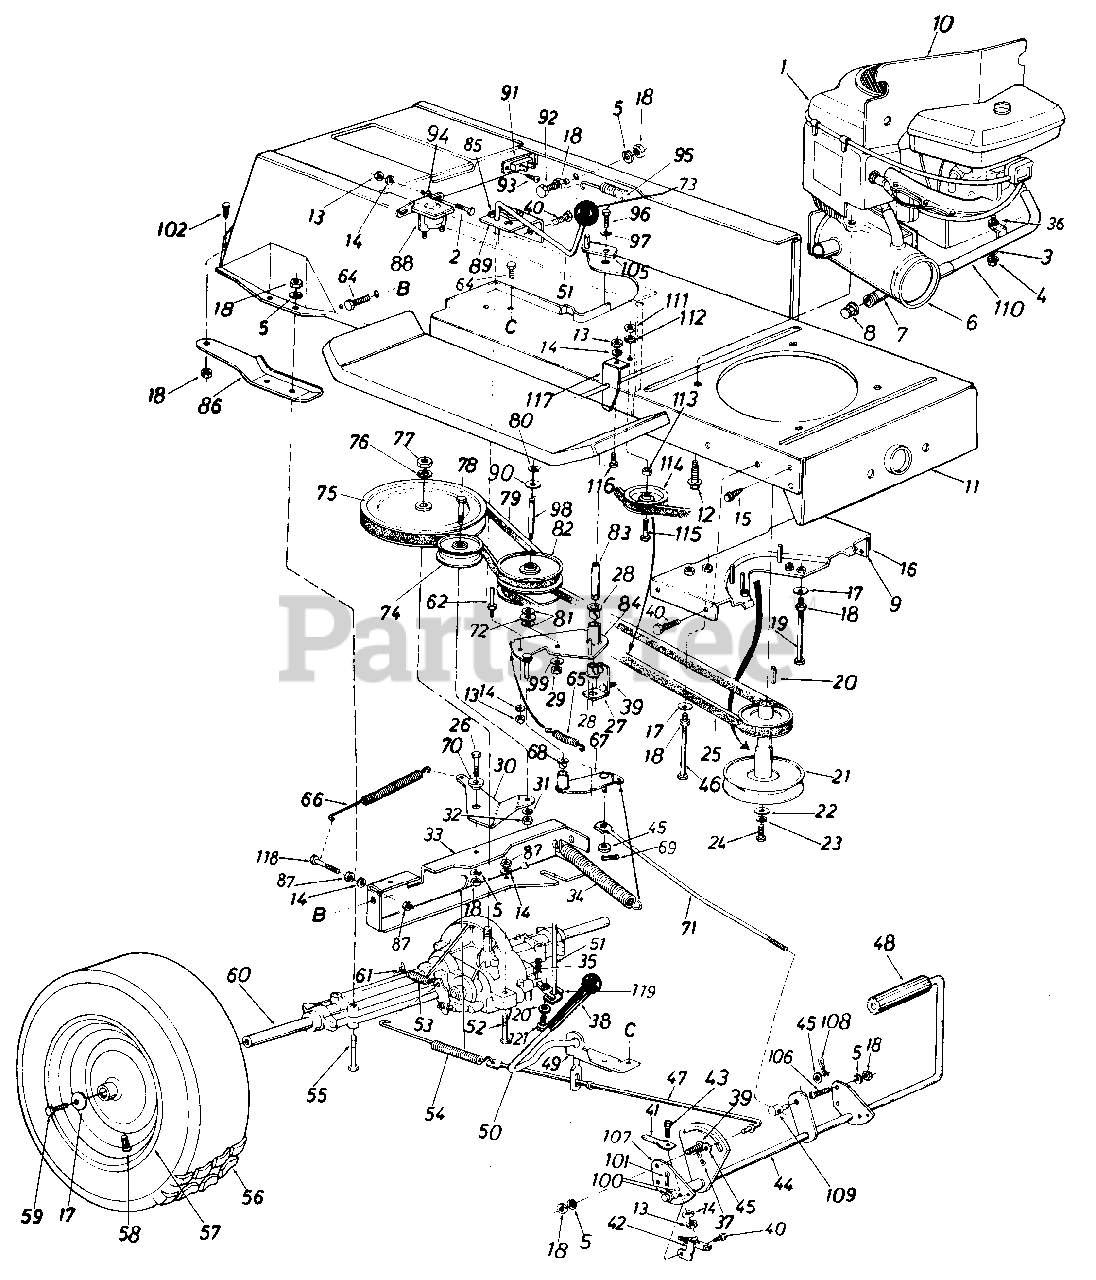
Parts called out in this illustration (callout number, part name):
1	Engine
2	Hex Bolt 1/4-20 x .62" Lg.
3	Special L-Wash. 5/16" I.D.
4	Hex Nut 5/16-18 Thd.
5	L-Wash. 5/16" I.D.
6	Exhaust Muffler
7	Pipe Nipple
8	Cap Oil Drain
9	Brake Cable Brk't.
10	Heat Shield
11	Lower Frame Ass'y.
12	Hex Wash. Hd. TT-Tap Scr. 3/8-16 x 1.25 Lg.
13	Hex Nut 1/4-20 Thd.
14	L-Wash. 1/4" I.D.
15	Hex Wash. Hd. AB-Tap Scr. 5/16" x.75" Lg.
16	Belt Guard Brkt. Ass'y.
17	Bell-Wash. .345" I.D. x .88"
18	Hex Nut 5/16-18 Thd.
19	Hex Bolt 5/16-18 x 4.00"
20	Sq. Key 1/4" x 1/4" x 2.00"
21	Engine Pulley
22	Fl-Wash. 7/16" I.D. x 1.25
23	L-Wash. 7/16" I.D.*
24	Hex Bolt 7/16-20 x 1.50" Lg.
25	Variable-Speed Belt
26	Hex Bolt 5/16-18 x .75" Lg.
27	Bearing Shaft Bracket Ass'y.
28	Flanged Nyliner Brg. 5/8" I.D. x .88" Lg.
29	Hex Nut 3/8-24 Thd.
30	Idler Bracket
31	L-Wash. 3/8" I.D.
32	Hex Nut 3/8-24 Thd.
33	Transaxle Support Brkt.
34	Ext. Spring .94" O.D. x 6.7
35	Inter. Cotter Pin
36	Fl-Wash. .34 I.D. x .62" O.D. x .033
37	Cotter Pin 3/32" Dia. x .75"
38	Grip-Black
39	Truss Mach. Scr. 5/16-18 x .75" Lg.
40	Hex Wash. Hd. Self-Tap Scr. 1/4-20 x .50" Lg.
41	Switch Actuator
42	Safety Switch
43	Hex Bolt 1/4-20 x 1.0" Lg.
44	Clutch & Brake Pedal Ass'y.
45	Fl-Wash.
46	Hex Bolt 5/16-18 x 4.5"
47	Brake Rod 20.9" Lg.
48	Foot Pad
49	Brake Lever Bracket
50	Hill Holder Brake Handle
51	Shift Lever Ass'y.
52	Hex Bolt 1/4-28 x 1.75" Lg.
53	Ext. Spring x 2.5" Lg.
54	Ext. Spring x 7.08" Lg.
55	Hex Bolt 5/16-18 x 2.75"
57	Wheel Rim Only
58	Air Valve
59	Hex Bolt 5/16-24 x .75" Lg.
60	Transaxle Complete-R.H.
61	Brake Return Spring Anchor
62	Belt Guard Pin 1/4-20 Thd.
64	Hex Wash. TT-Tap Scr. 5/16 x .62" Lg.
65	Ext. Spring
66	Ext. Spring .62" O.D. x 6.12"
67	Variable Speed Torque Brkt. Ass'y.
68	Flanged Bearing
69	Cotter Pin 3/32" Dia.
70	Shoulder Spacer .500" Dia. x.27" Lg.
71	Speed Control Link
72	Truss Bearing .56 Dia. x 1 .25"
73	Ball Knob
74	Fl-Idler Pulley 3.25" x 1.0"
75	1/2" "V"-Pulley 8.0" O.D. x .501 " I.D.
76	L-Wash. 1/2" I.D.
77	Hex Jam Nut 1/2-20 Thd.
78	Hex Bolt 3/8-24 x .75" Lg.
79	Variable-Speed Belt
80	Snap Ring .56" Dia.
81	Fl-Wash.
82	Variable Speed Pulley Ass'y. 5" O.D.
83	Bearing Shaft
84	Variable Speed Brkt. Ass'y.
85	Comp. Spring Clip
86	Transaxle Support Brkt.-R.H.
87	Hex Nut 1/4-28 Thd.
88	Solenoid
89	Shift Lever Bracket
90	Teflon Wash. .565" I.D. x 1.12" O.D.
91	Circuit Breaker
92	Hex Bolt 5/16-18 x 1.50" Lg.
93	Truss Hd. Phil. Scr. #10 x 1/2" Lg.
94	Ext. L-Wash. 1/4" I.D.
95	Ext. Spring .99" O.D. x 11.0"
96	Hex Bolt 3/8-24 x .75" Lg.
97	Bell-Wash. .38" I.D. x .88"
98	Shaft .56" Dia. x 3.875" Lg.
99	Bell-Wash. .39" I.D. x 1.12"
100	Fl-Wash.
101	Cotter Pin 3/32" Dia. x .75"
102	Hex Wash. Hd. Scr. 5/16-18 x.62" Lg.
105	Belt Guard
106	Hex Bolt 5/16-18 x .75" Lg.
107	Pedal Bracket
108	Cotter Pin 3/32 x .75"
109	Ferrule
110	Inlet Tube Ass'y.
111	Hex Nut 3/8"-16 Thd.
112	L-Wash. 3/8" I.D.
113	Fl-Wash. .390" I.D. x 1.12"
114	Fl-Idler w/Flanges 2.750
115	Hex Bolt 3/8-16 x 2.00" Lg.*
116	Hex Bolt 1/4-20 x .62" Lg.*
117	Spring Hanger Bracket
118	Hex Bolt 1/4-28 x 1.25" Lg.*
119	Shift Lever Link Ass'y.
121	Hex Bolt 1/4-28 x .62" Lg.
